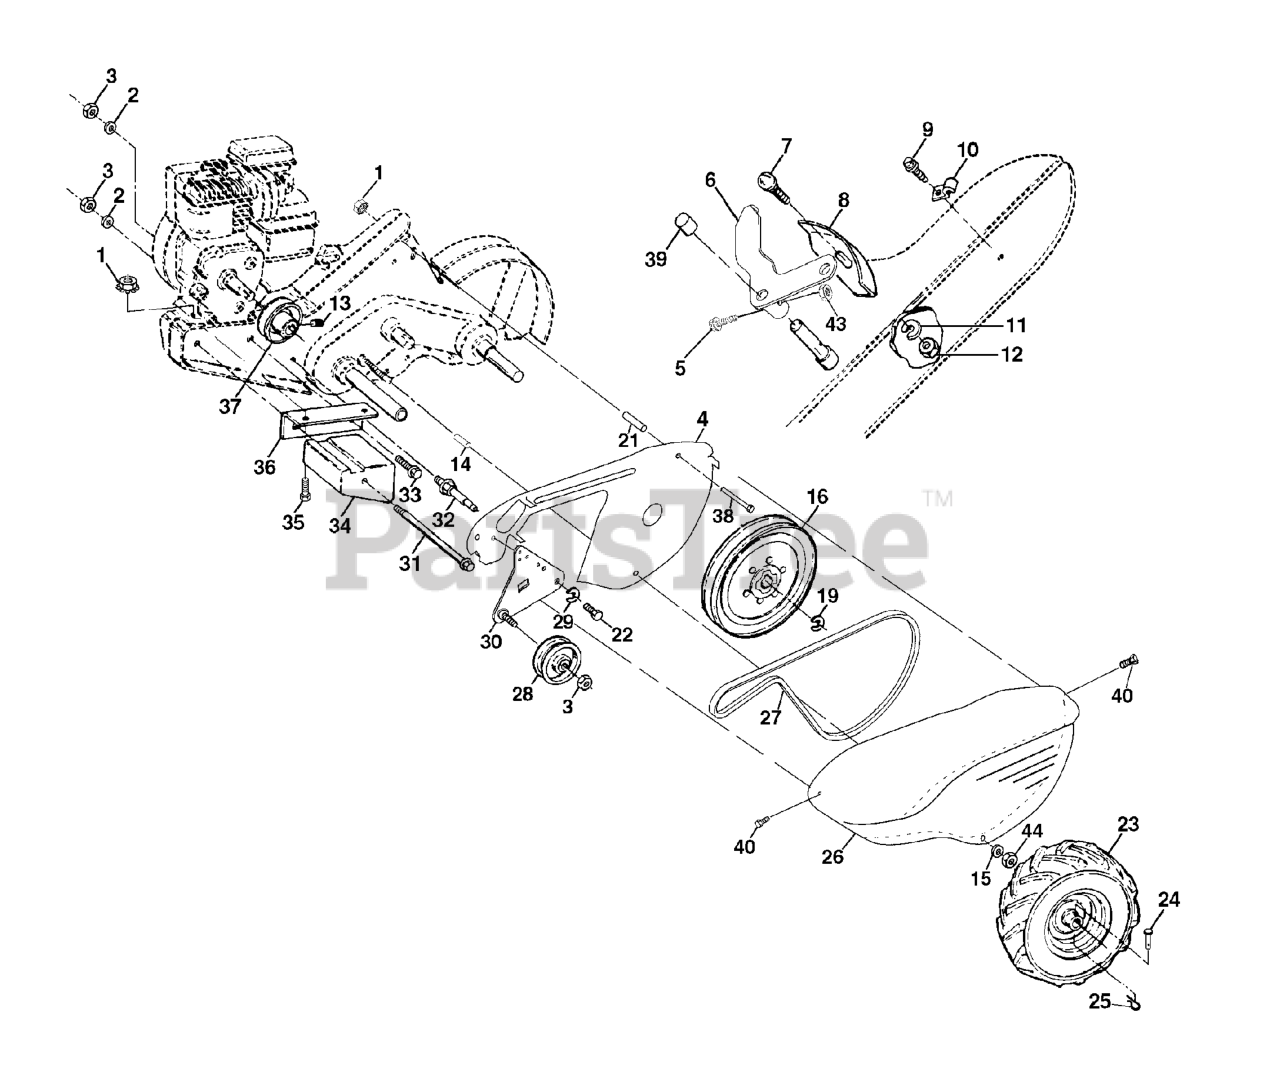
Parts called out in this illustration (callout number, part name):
1	NUT
2	WASHER, LOCK 3/8
3	NUT.HEX.3/8-16UNC
4	SHIELD
5	SCREW, SHIFT LEVER
6	LEVER ASM CRT
8	PANEL.INDICATOR.SHIFT.BLACK
9	Screw, Hex, Washer Head, Slotted #10-24 x 1/2
10	CONDUIT.CLIP.PLATED
11	LOCKWASHER
12	NUT
14	SPACER CRT
15	WASHER
16	SHEAVE, TRANSMISSION
19	RETAINING RING LT
21	SPACER-SPLIT.327 X .42
23	TIRE.16X4-8.CHEVRON.TILLER
23	RIM
23	VALVE STEM LT
24	RIVET,DRILLED
25	RETAINER M
26	RP BELT GUARD
27	V-BELT
28	PULLEY-IDLER TI
30	BRACKET.ASM.IDLER.BLACK
31	BOLT.FIN.HEX.3/8-16UNC
32	SHIFT ARM CRT
33	BOLT
34	COUNTERWEIGHT.LH.CRT
35	Bolt, Hex 5/16-18 x 2
36	BRACKET LH CRT
37	RP.ENGINE PULLEY
38	BOLT
39	CAP.PLUNGER.BLACK
40	SCREW.HEX.WSH.SLT.#10-24X.50
44	NUT.71038.31-18.HEX.NYLOCK
